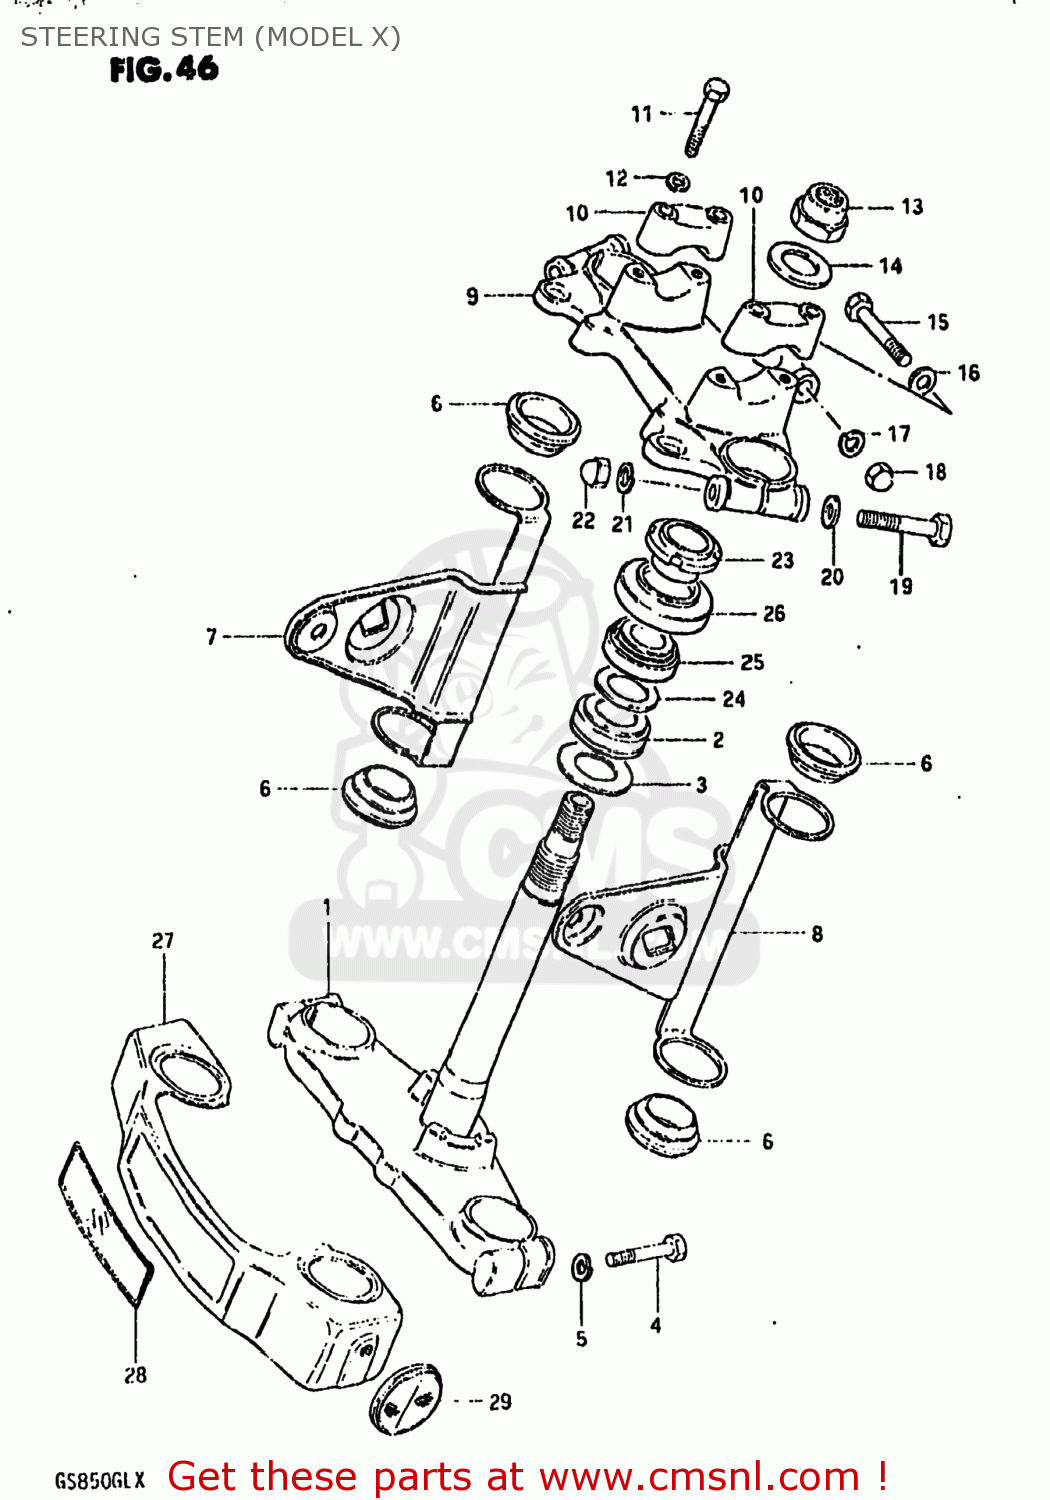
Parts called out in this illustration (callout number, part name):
1	STEM,STEERING
2	BEARING
3	WASHER,THRUST
4	BOLT
5	LOCK WASHER
6	CUSHION,HEADLAMP BRACKET
7	BRACKET,HEADLAMP,RIGHT
8	BRACKET,HEADLAMP,LEFT
9	HEAD,STEERING STEM
10	HOLDER,HANDLE(BLACK)
11	BOLT
12	LOCK WASHER
13	NUT,FR FORK UPR BRACKET
14	WASHER
15	BOLT 10X55
16	WASHER
17	LOCK WASHER
18	NUT, LOWER LH
19	BOLT 8X50
20	WASHER
21	LOCK WASHER
22	NUT
23	NUT,STEERING STEM
24	WASHER(18.5X24X1)
25	TAPER,ROLLER BEARING
26	DUST SEAL,STEERING,UPPER
27	COVER,FRONT FORK
28	EMBLEM,FR FORK COVER
29	REFLEX REFLECTOR,RR
